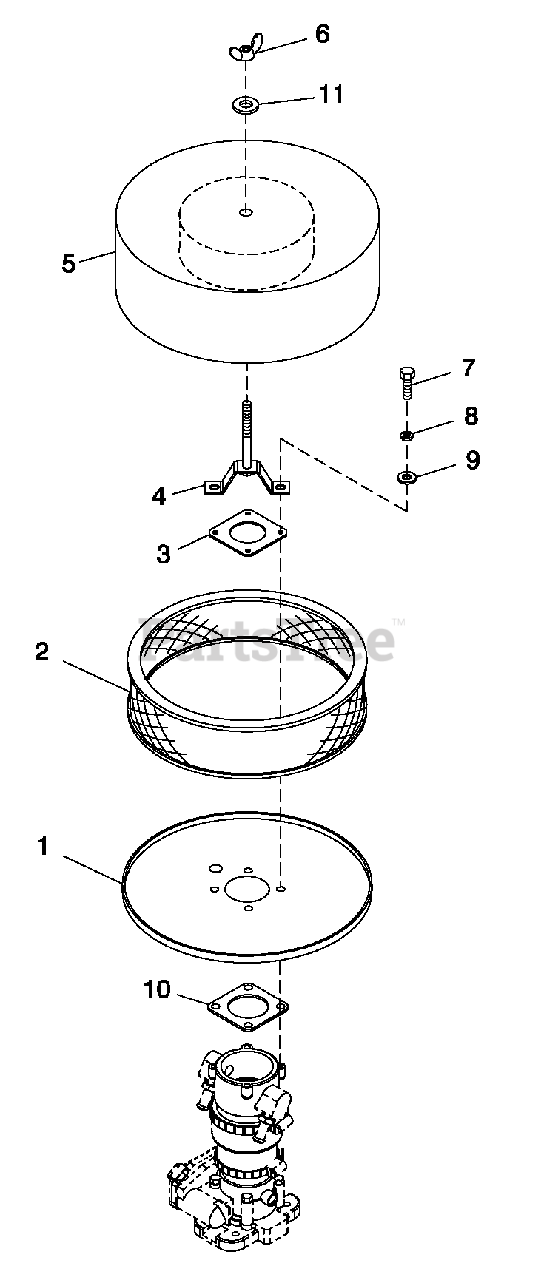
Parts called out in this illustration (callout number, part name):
1	AIR CLNR BTM PLT W/CPLR 8.1L
2	ELEMENT AIR FILTER
3	TOP PLATE VENTURI
4	HOLD DOWN AIR CLEANER PLATED
5	PLATE AIR CLEAN TOP 5.4L/6.8L
6	NUT WING 1/4-20 NYLK
7	SCREW HHC M6-1.0 X 16 G8.8
8	WASHER LOCK M6-1/4
9	WASHER FLAT M6
10	GASKET MIXER BODY
11	WASHER FLAT 1/4-M6 ZINC
